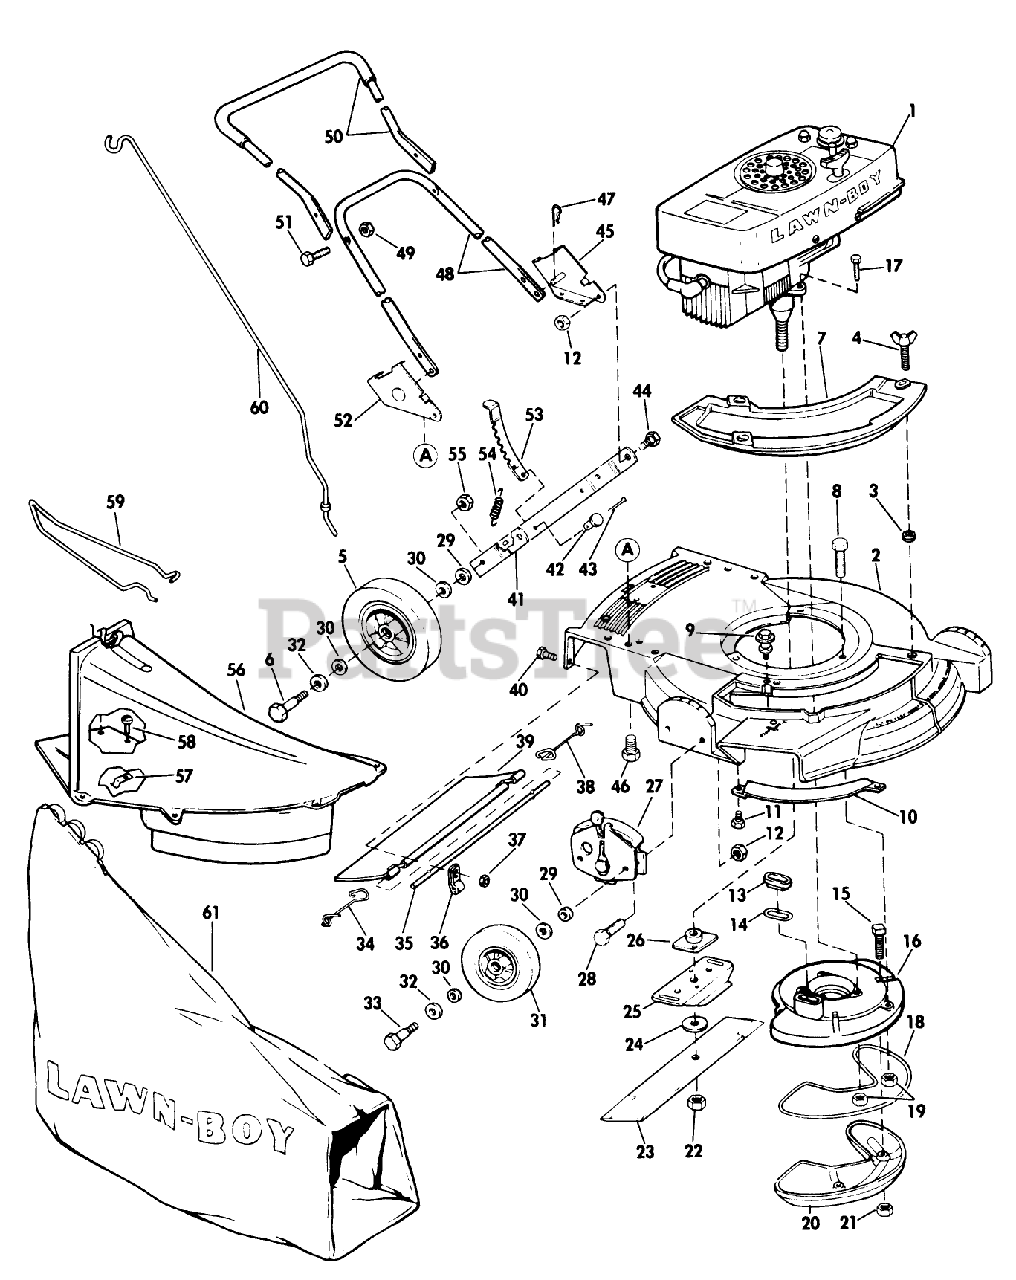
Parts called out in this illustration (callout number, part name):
4	WING SCREW LAWRE
6	BOLT
8	SCREW
10	TOE BAR 19"
10	BAR-TOE
12	NUT
13	SLEEVE
14	GASKET S
19	NUT-LOCK F
22	NUT-BLADE
24	WASHER
26	PLATE AND COLLAR ASM
29	WASHER WROUGHT
30	WASHER
31	WHEEL & TIRE KIT
32	SPACER
33	BOLT WHEEL
34	SPRING;TRAILING SHIELD RH
35	ROD T/SHIELD ADV WIRE
35	ROD 21" ADVANCE
36	CLAMP ROD KMC
37	Nut
38	SPRIG T/SHLD ASOC
44	BOLT-SHOULDER
46	SCREW
47	HAIR PIN
49	Nut-Handle
50	Handle-Top (Model 5081 Only)
51	SCREW
54	SPRING N.A.S
55	LOCKNUT
60	ROD GRASSBAG
61	89802 LB WHOLE GOODS
